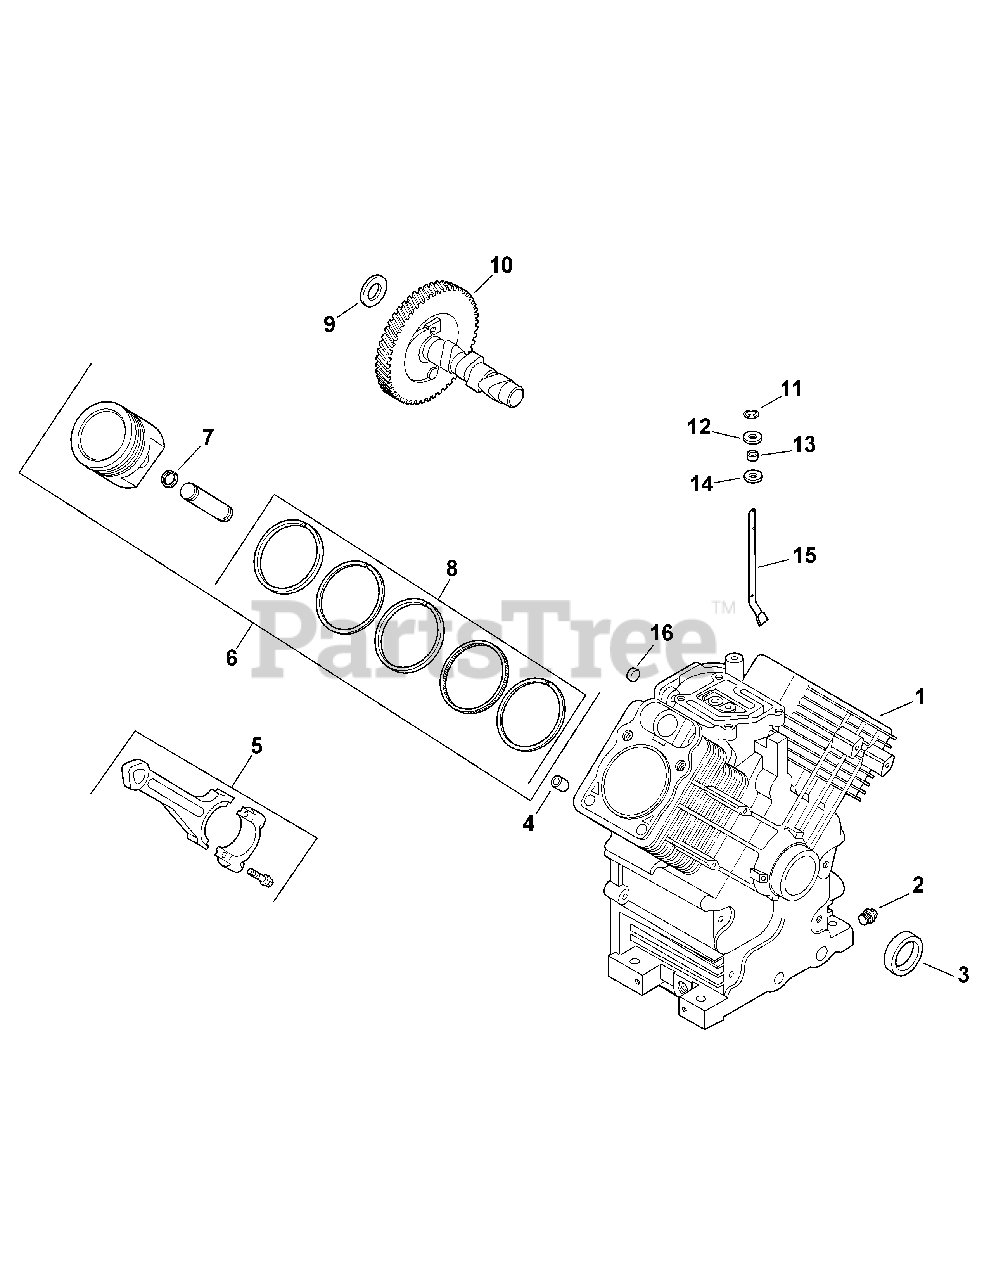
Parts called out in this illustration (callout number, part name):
1	Crankcase (Use Miniblock)
2	Plug, hex. head 3/8" (2)
3	Seal, front oil
4	Pin, locating (6)
5	Connecting Rod (Std.) (2)
6	Piston w/Ring Set (Std.) (2) (Includes 7,8)
7	Retainer, piston pin (4)
8	Ring Set (Std. & .08)
9	Shim, camshaft (A.R.) red
10	Camshaft
11	Retainer, ring
12	Washer, plain 9 mm
13	Seal, governor cross
14	Washer, plain 1/4"
15	Shaft, governor cross
16	Plug, cup
